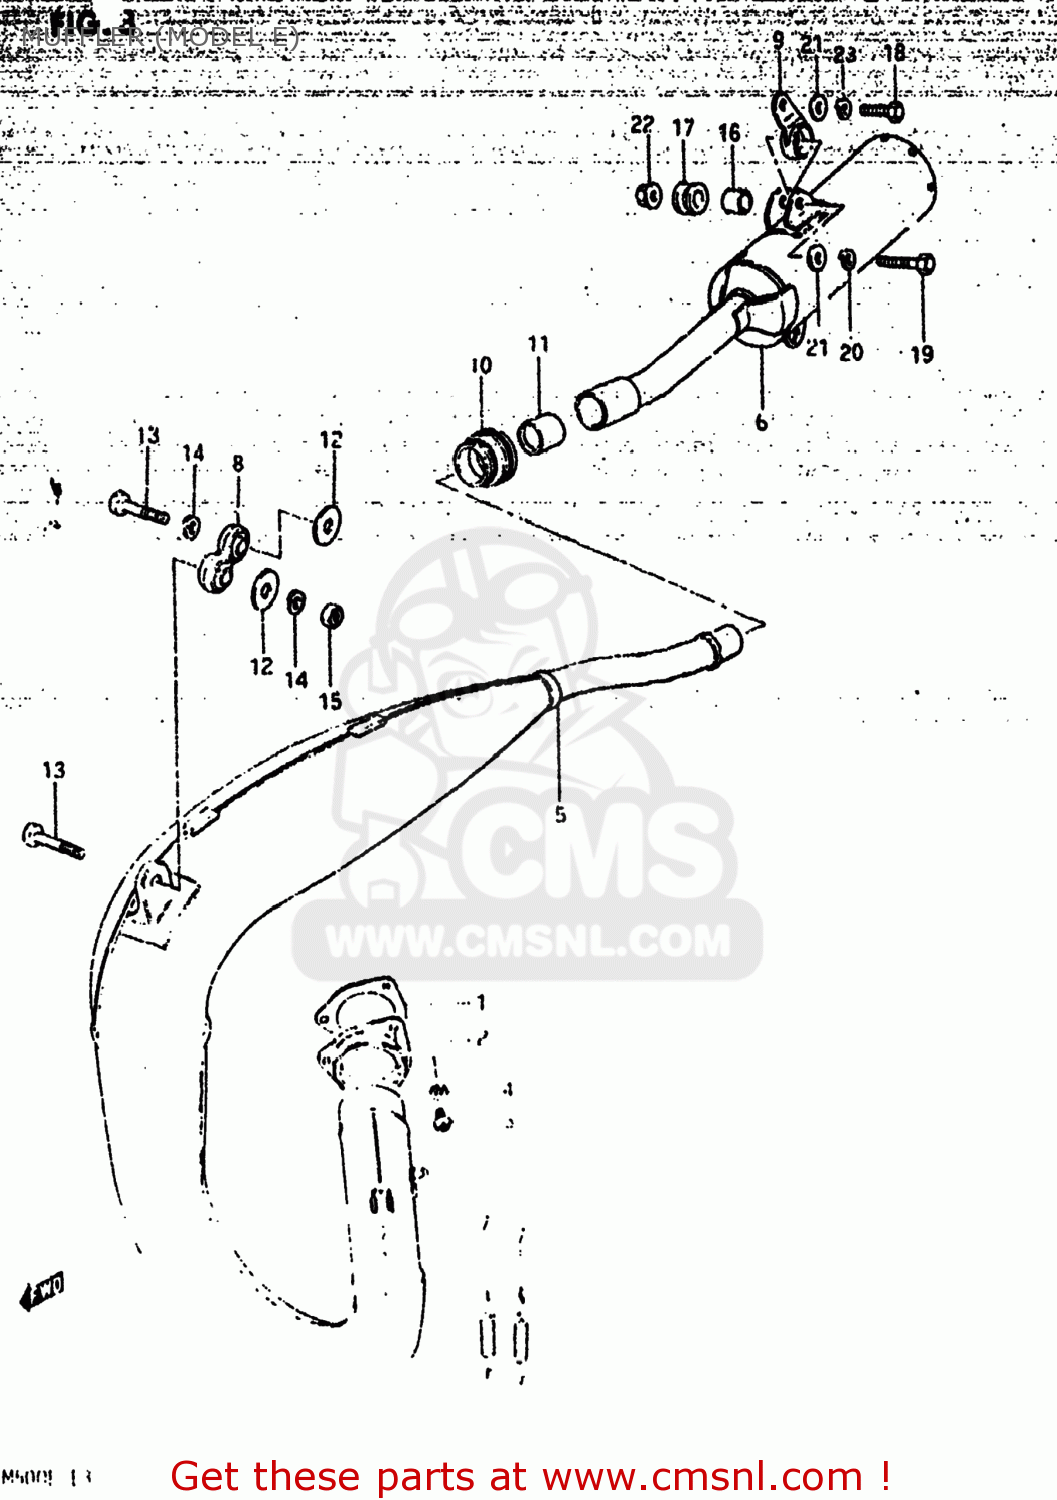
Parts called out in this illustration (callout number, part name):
1	GASKET,EXHAUST PIPE (MCA)
2	FLANGE,EXHAUST PIPE
3	SCREW
4	LOCK WASHER
5	BODY,MUFFLER
6	MUFFLER ASSEMBLY,SECOND
7	SPRING
8	DAMPER,MUFFLER
9	DAMPER,MUFFLER SUPPORT
10	CONNECTOR,SECOND MUFFLER
11	GASKET,SECOND MUFFLER (NA) (NAS)
12	WASHER
13	BOLT(8X32)
14	LOCK WASHER
15	NUT 8MM
16	SPACER (8.6X12X17.5)
17	CUSHION
18	BOLT
19	BOLT
20	LOCK WASHER
21	WASHER
22	NUT
23	WASHER,LOCK,8.
